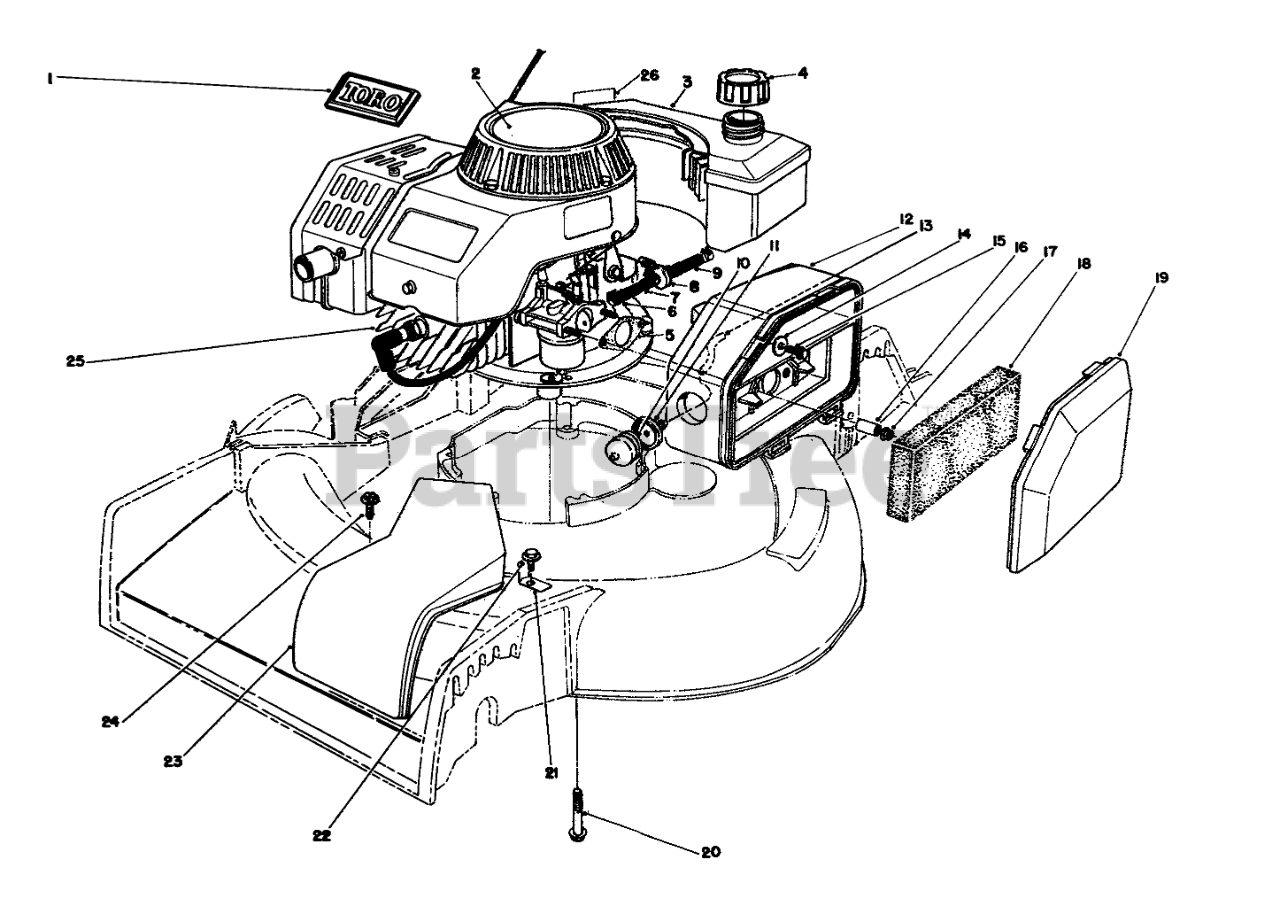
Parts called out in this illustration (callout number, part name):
1	TORO LOGO PLT
2	DECAL
3	FUEL TANK ASM
4	GAS CAP ASM
5	GASKET-AIR CLEANER
6	CLAMP-FUEL LINE
7	HOSE-FUEL
8	FILTER-FUEL
9	HOSE-FUEL
10	BULB-PRIMER
11	BODY-PRIMER
12	BODY-AIR CLEANER
13	HOSE-PRIMER
14	WASHER-FLAT
15	SCREW-HH
16	SPACER
18	ELEMENT-AIR CLEANER
19	COVER-AIR CLEANER
20	SCREW-HHF, WHIZ
21	BELT GUIDE
22	SCREW-HWHTF
23	Cow-Belt
24	SCREW
25	Engine (Complete)
26	Decal-Maintenance
